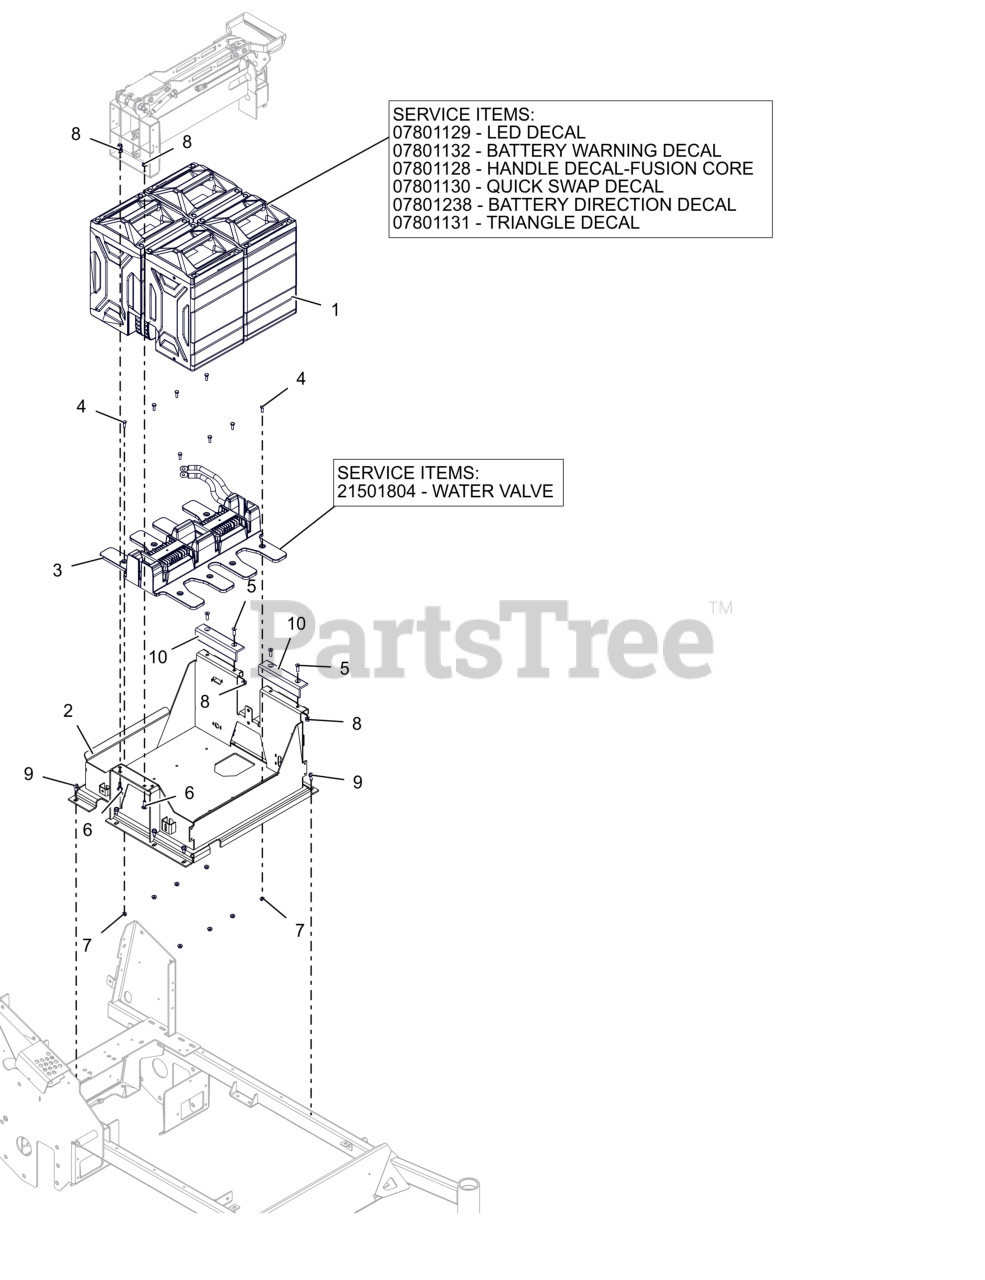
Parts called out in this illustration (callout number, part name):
1	KIT, EV BATTERY
1	DECAL, BATTERY LED
1	BATTERY WARNING DECAL
1	DECAL, BATTERY HANDLE
1	DECAL, BATTERY QUICKSWAP
1	DECAL, BATTERY INSTALL DIRECTION
1	DECAL, BATTERY OBLIQUE
2	WLDMT- BATTERY TRAY
3	BASE, BATTERY BUSSBAR
3	VALVE, WATER
4	BLT, HEX .25-20X.75 G5 ZCC
5	SCR, MCH .312-18X1.00 SFH ZCC
6	BLT,RHSN .31-18X1.00 G5 ZCC
7	NUT-LK-CTR-FLG .25-20 ZC120
8	NUT,LK-CTR-FLG .31-18 GF ZCC
9	SCR,TAP .312-18X.75 HWH TR ZCC
10	EDGE, PROTECTIVE - BATTERY
